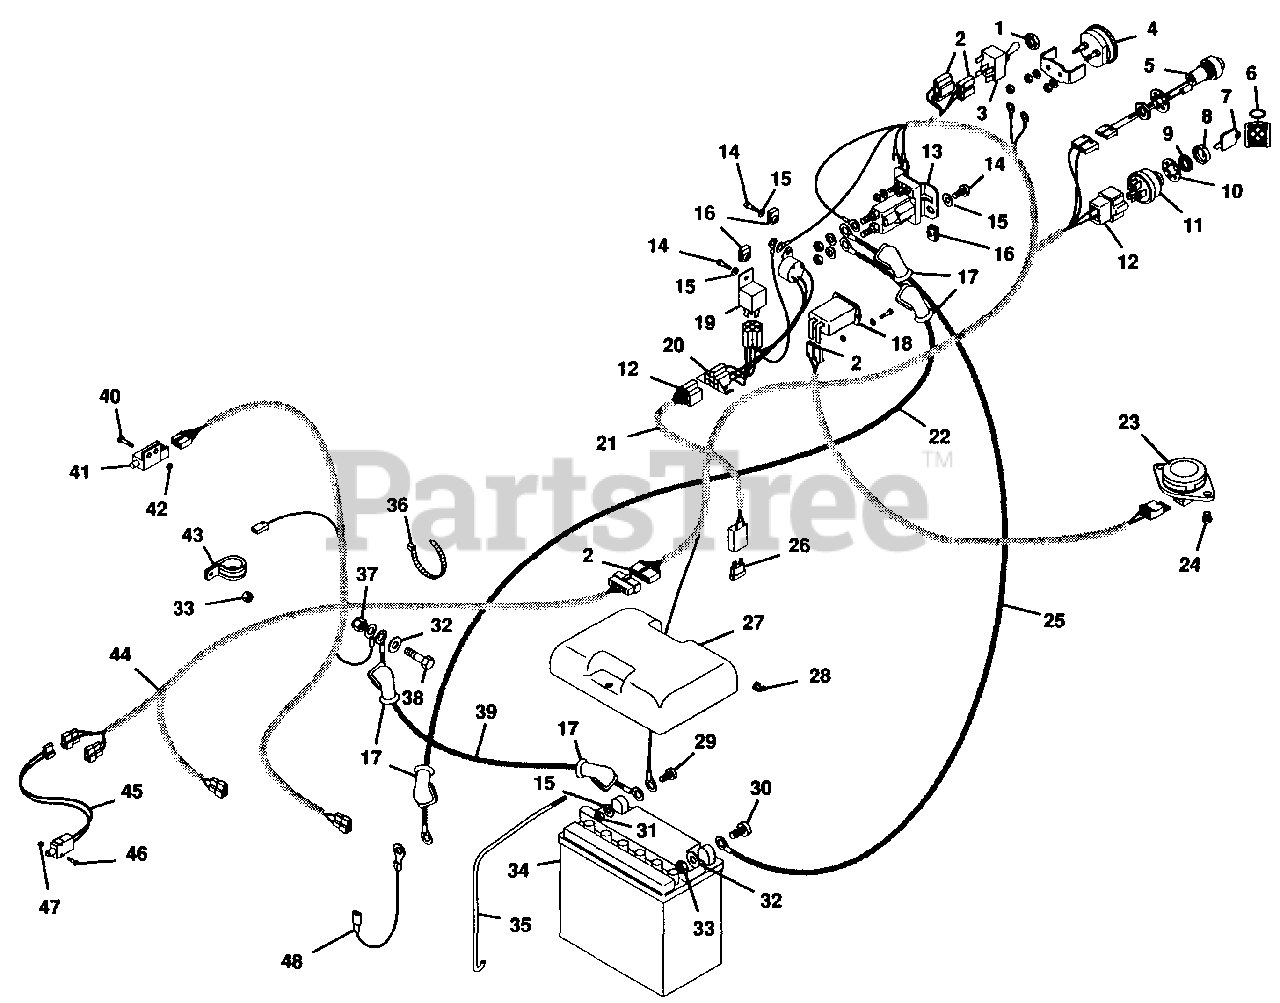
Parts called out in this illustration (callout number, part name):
1	NUT, 1/2-27
2	TERMINAL
3	SWITCH, PTO
4	GAUGE, AMMETER
5	LIGHT, INDICATOR
6	CHAIN, KEY
7	KEY, IGNITION SWITCH
8	BOOT, 9/16 SWITCH
9	NUT, JAM 9/16-24
10	WASHER, LOCK 9/16 INT. TOOTH
11	SWITCH, IGNITION
12	CONNECTOR
13	SWITCH, MAGNETIC
14	SCREW, MACHINE 1/4-20 PHD
15	WASHER, FLAT .281X.625X.065
16	NUT, SPEED 1/4-20
17	BOOT, BATTERY CABLE
18	HOURMETER
19	RELAY
20	MODULE, TIME DELAY
21	HARNESS, WIRING
22	ASSEMBLY, CABLE
23	SWITCH, SEAT
24	SCREW, MACHINE 1/4-20
25	CABLE, BATTERY TO SOLENOID
26	FUSE, 25 AMP
27	COVER, BATTERY
28	NUT, WING 1/4-20
29	BOLT, HEX 1/4-20X.75
30	BOLT, HEX 5/16-18X.75
31	NUT, HEX 1/4-20
32	WASHER, FLAT .344X.688X.065
33	NUT, HEX 5/16-18
34	BATTERY, 12 VOLT
35	ROD, BATTERY
36	TIE WRAP, BLACK
37	NUT, LOCK 5/16-18
38	BOLT, HEX 5/16-18X1.00
39	CABLE, NEGATIVE BATTERY
40	SCREW, MACHINE 10-24X.625 PHD
41	SWITCH, INTERLOCK
42	NUT, LOCK 10-24
43	CLAMP, STEEL .625
44	HARNESS, WIRING KOHLER
44	HARNESS, WIRING ONAN
45	SWITCH
46	SCREW,6-32X.875 PHCR
47	NUT, MACH. LOCK 6-32
48	ASSEMBLY, CABLE
